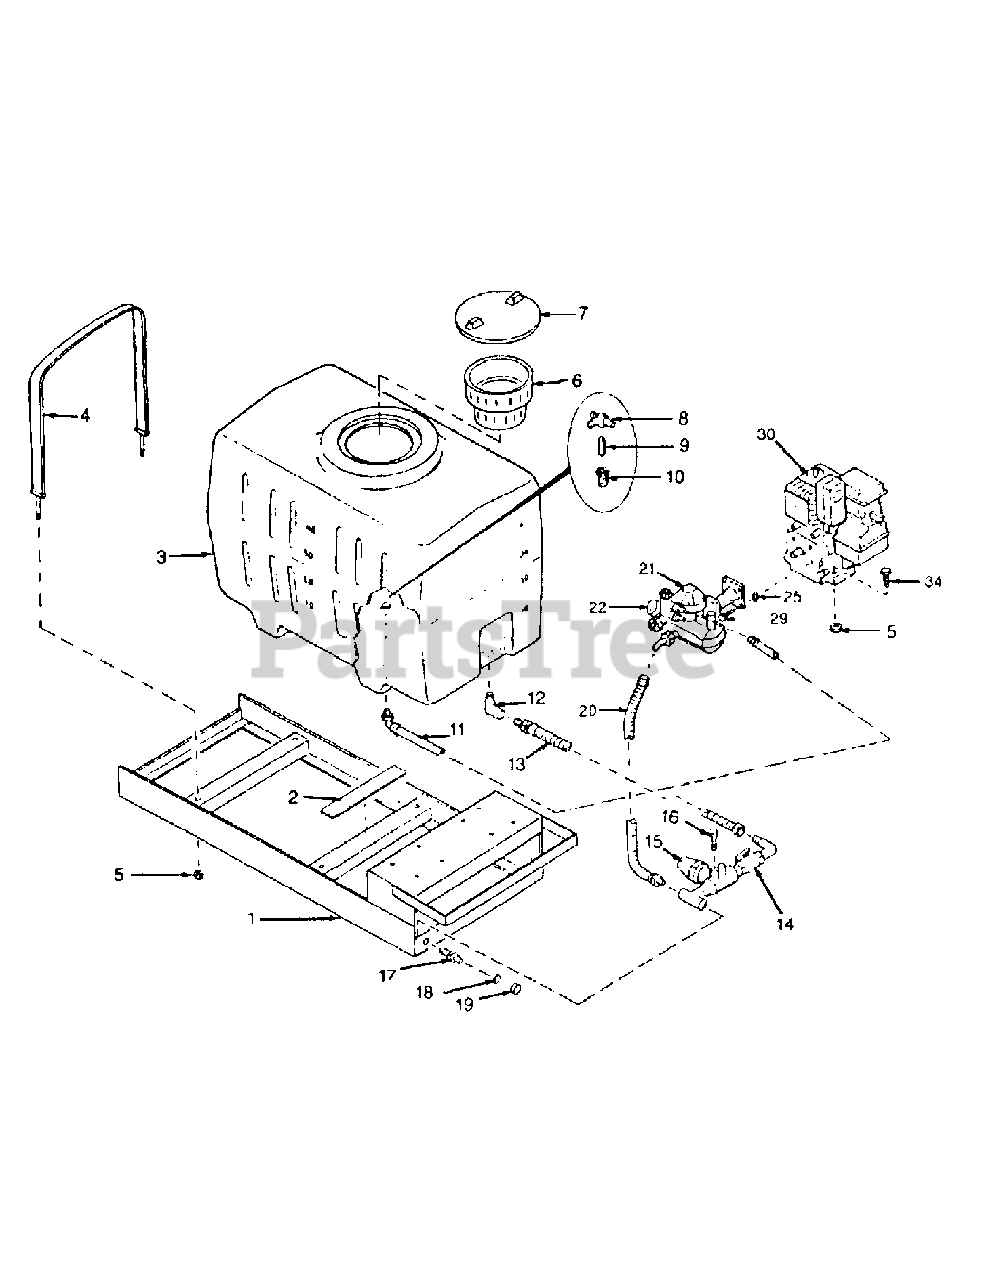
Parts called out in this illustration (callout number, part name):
1	Frame
2	Foam, Adhesive Backed, 4"x 1/4'x 16-1/2
3	Rect. Poly Tank, 50-Gallon
3	Fillwell, 1 0", Threaded
4	Tank Strap w/2 T-Bolts
5	Hex Nut, 5/16-18 Nylock
6	Strainer Basket 10"
7	Tank Lid, 10"
8	Agitator, Triple Jet, Brass
9	Nipple, 1/4 x Close, Brass
10	Reducer, 1/2 MPT x 1/4 FPT, Brass
11	Agitator Hose
12	Street Elbow, 9O Degree, 3/4 MPT x 3/4 FPT, PVC
13	Suction Hose, Tank to Manifold
14	Manifold Assembly
15	Line Strainer, 30 Mesh, 3/4 FPT x 3/4 FPT, PVC
15	Repair Kit
15	32 Mesh Screen
15	50 Mesh Screen
15	100 Mesh Screen
16	Cap Screw, 8MM-1.25 x 12 MM, Hex Hd:, Serrated Flange
17	Adapter, 3/4 MPT x 3/4 NH(M), Brass
18	Hose Washer, 3/4
19	Hose Cap, 3/4 NH(F), Brass
20	Suction Hose, Manifold to Pump
21	Pump, Twin Diaphragm
21	Pump, Diaphragm Repair Kit
22	Control Unit
25	Flat Washer, 5/16
29	Cap Screw, 5/16-24 x 3/4 Hex Hd
30	Engine, 4-HP, KAW., Recoil Start
30	Air Filter for KAW. Engine
30	Spark Plug for KAW. Engine
34	Cap Screw, 5/16-18 x 1-3/4 Hex Hd.
